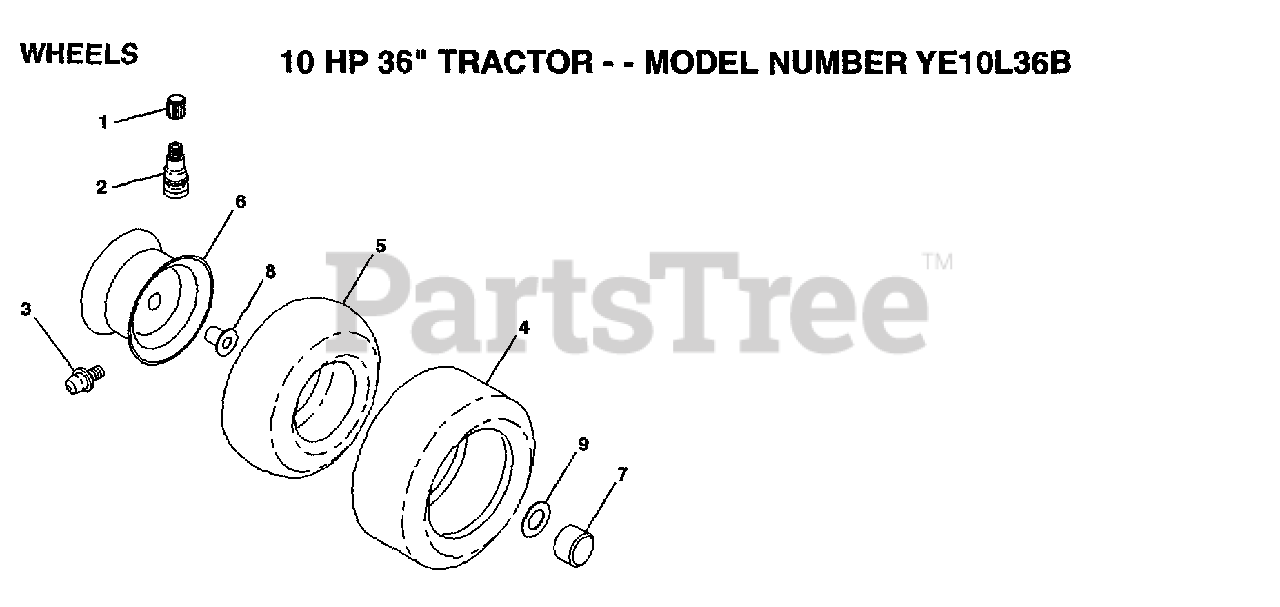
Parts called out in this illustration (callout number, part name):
1	VALVE CAP
2	VALVE STEM LT
3	FITTING LT
5	TUBE.5.3/4.5/6
7	HUB CAP
8	"FLANGE, BEARING"
9	WASHER
